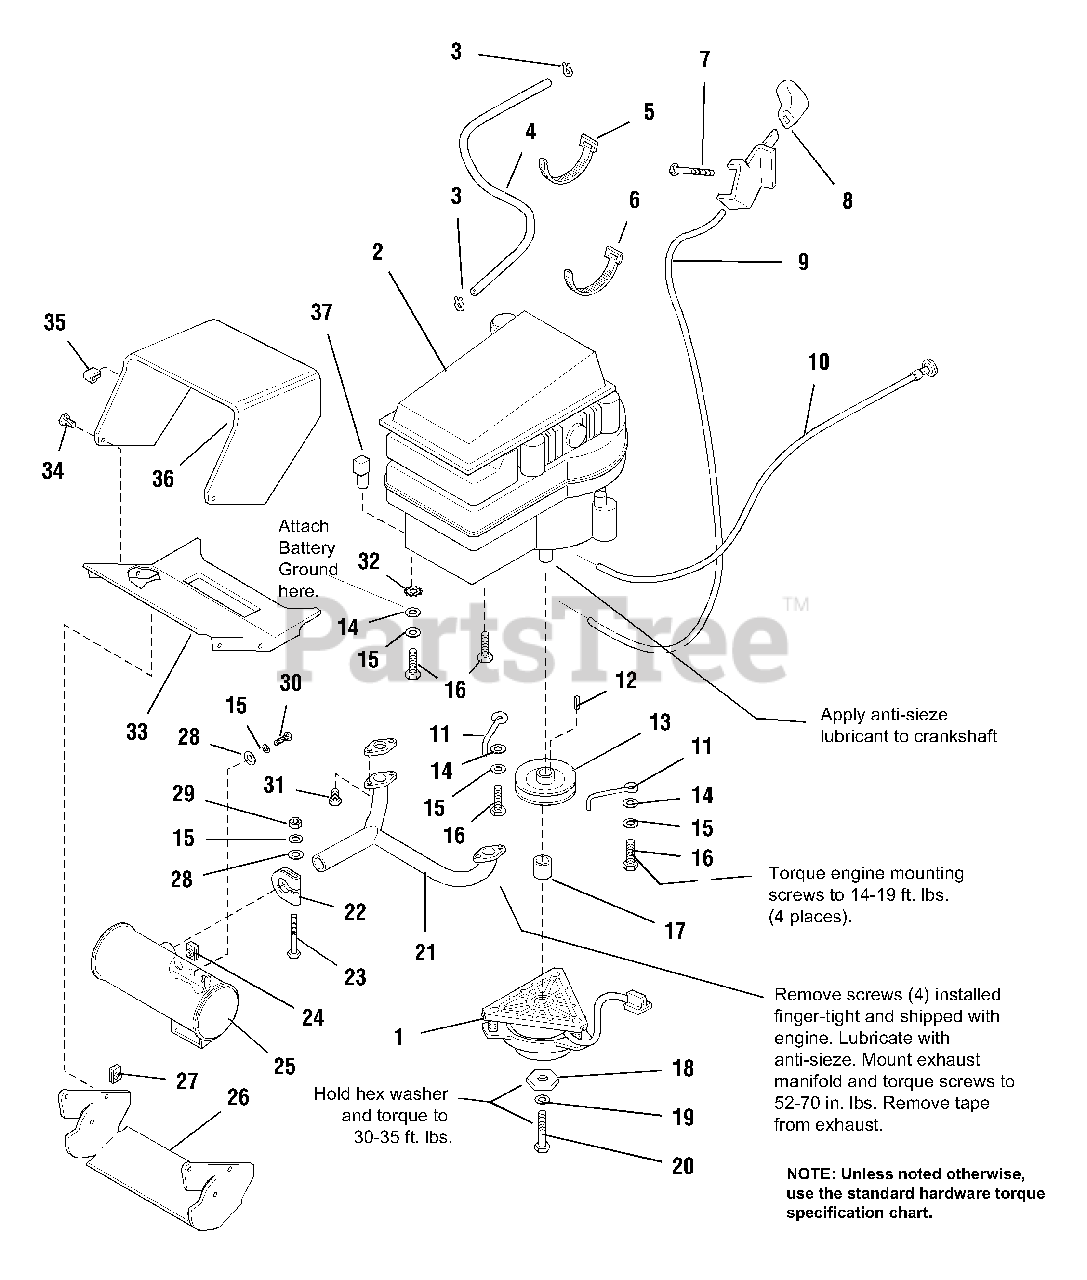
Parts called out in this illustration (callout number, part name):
1	ELECTRIC CLUTCH
2	ENGINE 17HP Kawasaki, Liquid Cooled
3	CLAMP, Hose
4	HOSE, Fuel, 38" Long
5	TIE, Self Locking
6	Tie, Self Locking
7	SCREW, Plastite, 1/4-10 x 1/2
8	KNOB, Throttle
9	THROTTLE & CABLE ASSY.
10	CABLE, Choke Control
12	KEY, Hi-Pro
13	PULLEY ASSY.
14	WASHER, Plain, 5/16
15	LOCKWASHER, 5/16
16	CAPSCREW, Hex Hd., M8 - 1.25 x 40mm
19	LOCKWASHER, 7/16
20	CAPSCREW, Hex Hd., M10 - 1.5 x 100mm
21	MANIFOLD, Exhaust
22	CLAMP, Muffler
23	CARRIAGE BOLT, 5/16-18 x 2-3/4
24	NUT, Pal, 5/16-18
25	MUFFLER ASSY.
26	DUCT, Lower Muffler
27	NUT, Pal, 1/4-20
28	WASHER, Plain, 11/32
29	NUT, Hex, Full, 5/16-18
30	CAPSCREW, Hex Hd., 5/16-18 x 1
31	SCREW, Metric
32	LOCKWASHER, Ext. Tooth, 5/16
33	DUCT, Upper Muffler
34	SCREW, Flange Whiz, 1/4-20 x 5/8
35	CLIP
36	DUCT, Upper
37	VALVE, Oil Drain
